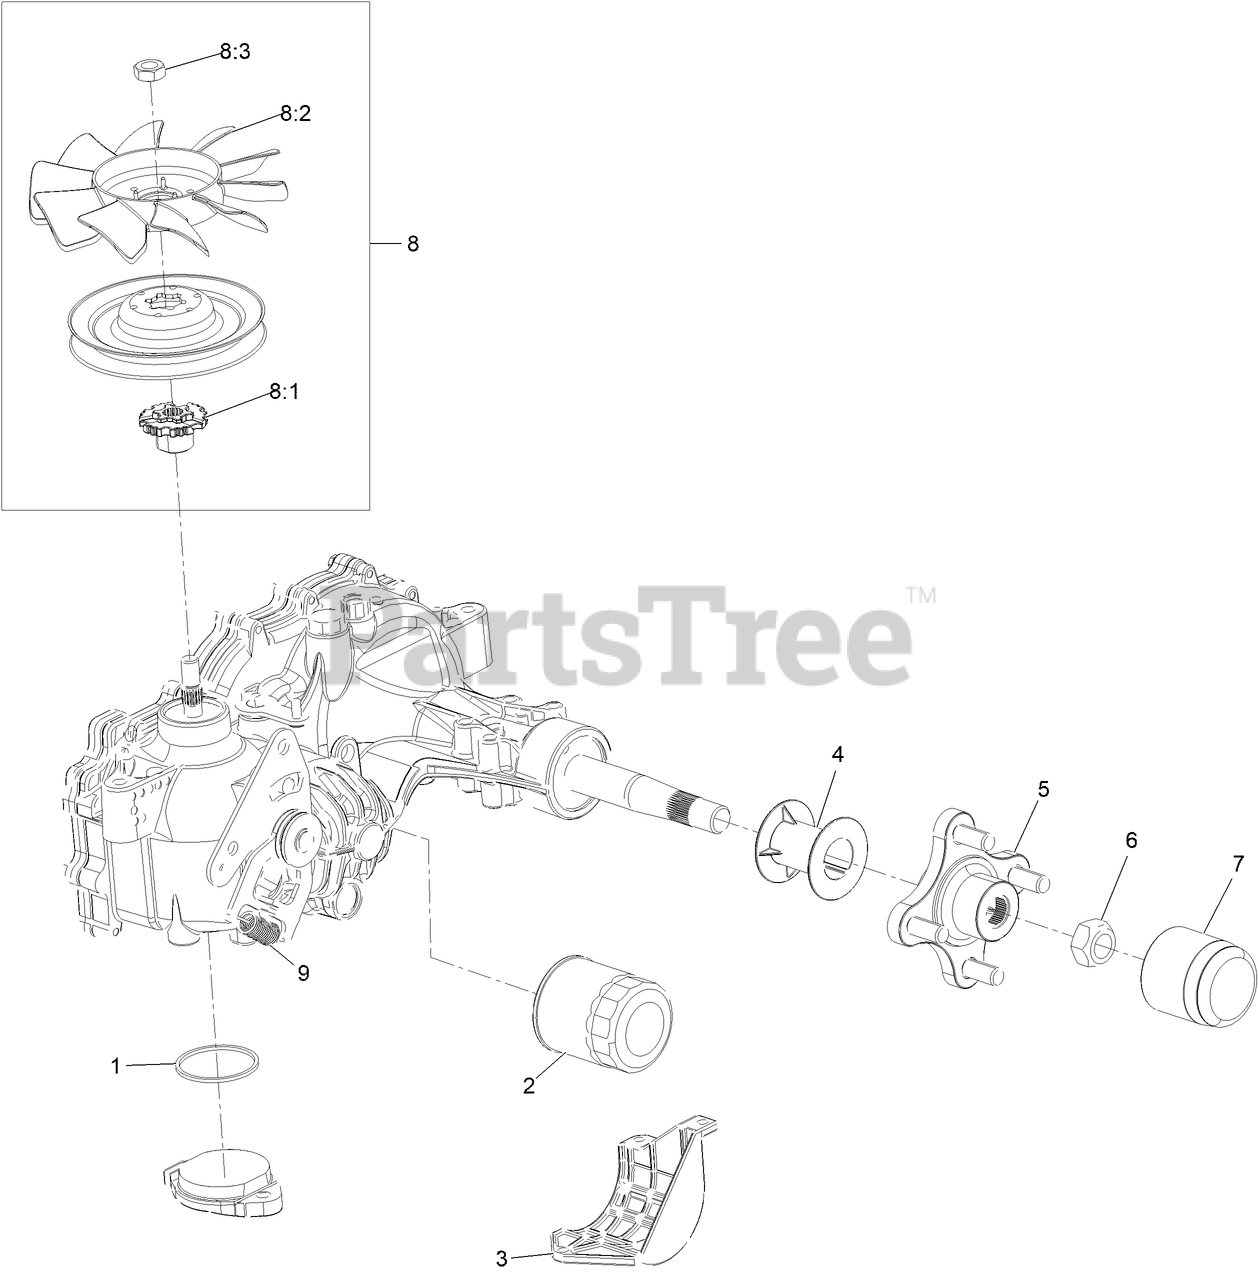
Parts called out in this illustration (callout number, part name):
1	O RING-SEAL
2	ELEMENT-OIL FILTER, HYD
3	GUARD-FILTER, LH
4	TUBE-AXLE
5	HUB-OFFSET
6	NUT-HUB
7	CAP-AXLE, LONG
8	FAN AND PULLEY KIT
8:1	HUB-FAN
9	SPRING-EXTENSION
